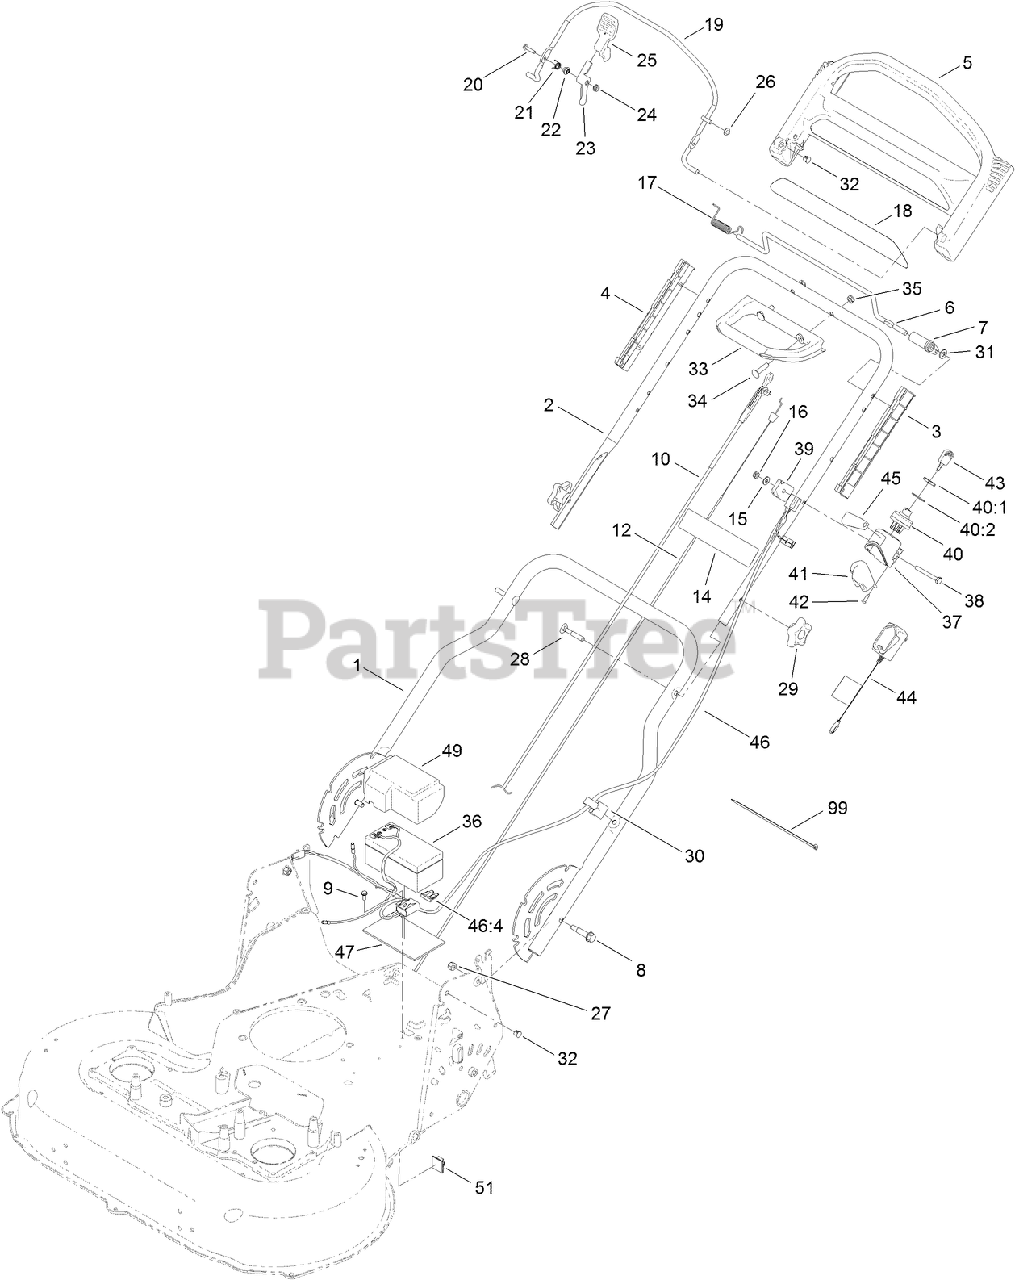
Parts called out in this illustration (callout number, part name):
1	HANDLE-LOWER
2	HANDLE-UPPER
3	GUIDE-LH
4	GUIDE-RH
5	HANDLE-CONTROL
6	BAR-CONTROL, TRACTION
7	LEVER-TRACTION
8	BOLT-SHOULDER, HHF
9	SCREW-TAPTITE
10	CABLE-BRAKE, BBC
12	CABLE-TRACTION
14	DECAL-WARNING
15	WASHER-FLAT
16	NUT-LOCK, NI
17	Spring-Torsion
19	BAIL-BRAKE
20	SCREW-HWH
21	SPRING-TORSION
22	SPACER
23	LEVER
24	NUT-LOCK, FLANGE
26	NUT-SPEED
27	NUT-LOCK, NI
28	SCREW-HANDLE
29	KNOB-HANDLE
30	GUIDE-CABLE
31	WASHER-PLAIN
32	Plug-Dome
33	HANDLE-ASSIST, TRACTION
34	BOLT-CARRIAGE
35	NUT-LOCK, NI
36	BATTERY-WET
37	HOUSING-SWITCH, KEY
38	SCREW-HH
39	ANCHOR-CABLE, UPPER
40	SWITCH-STARTER
40:1	NUT-HH
40:2	WASHER-TOOTH, INTERNAL
41	COVER-SWTCH
42	SCREW-PPH
44	CHARGER-BATTERY
45	DECAL-SWITCH, IGNITION
46	HARNESS-WIRE
46:4	FUSE-40 AMP
47	FOAM-BATTERY
49	COVER-BATTERY
51	GUIDE-CABLE
99	TIE-CABLE
